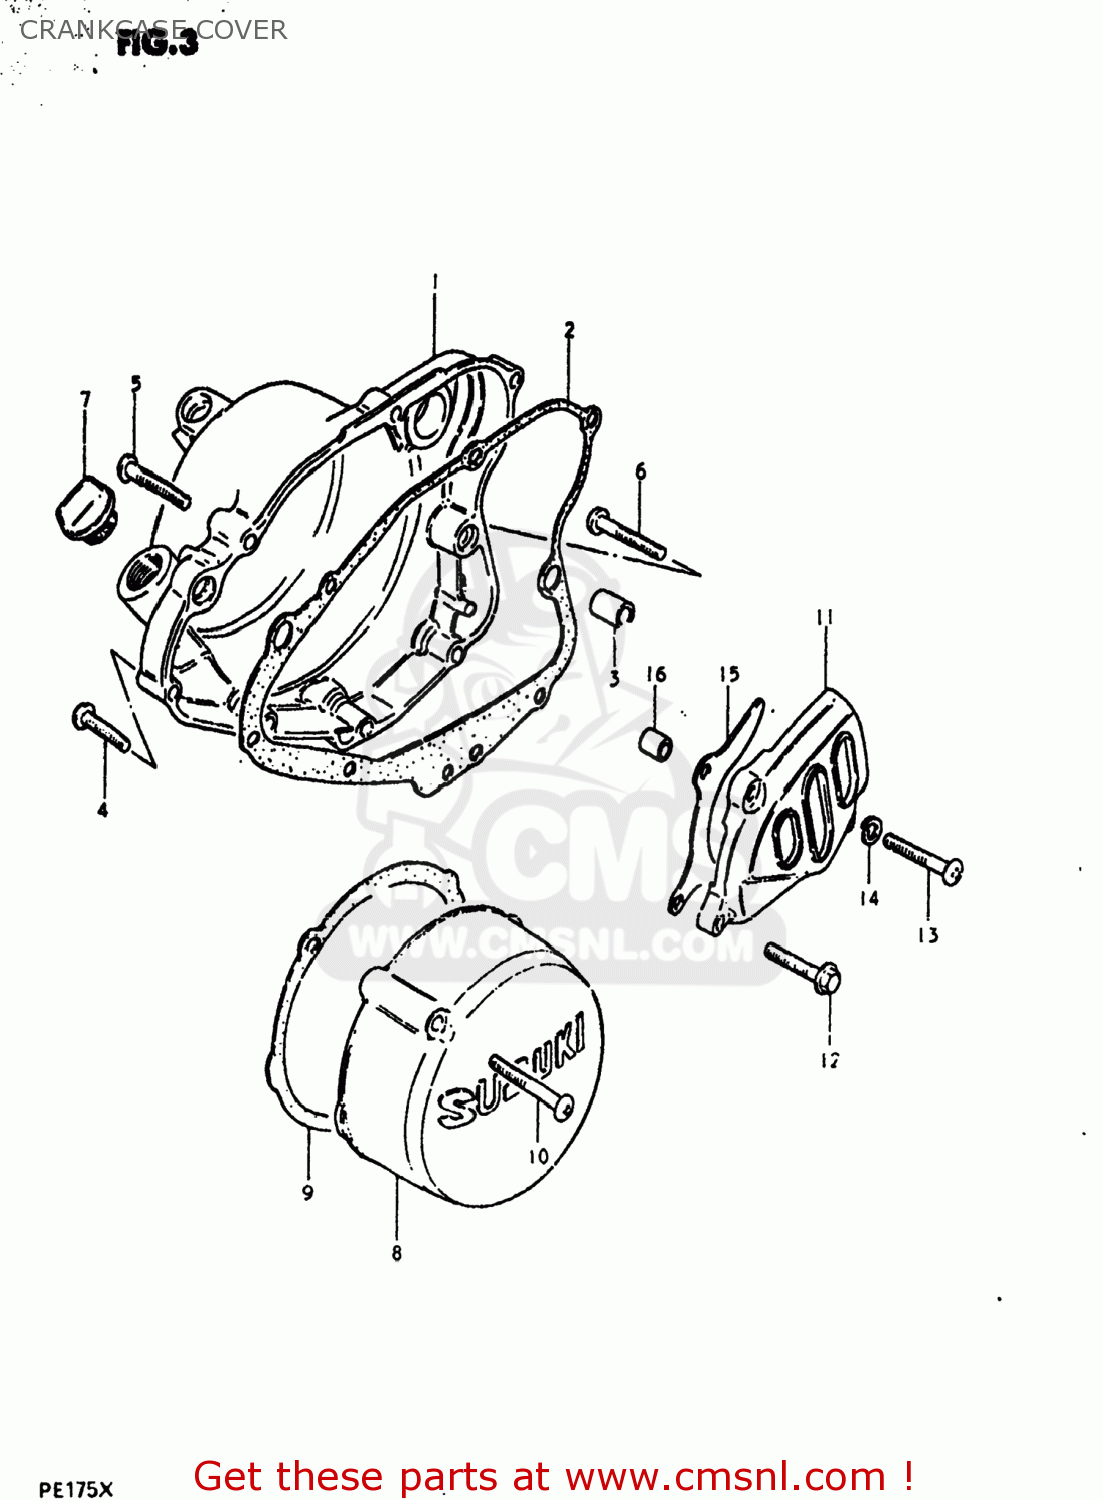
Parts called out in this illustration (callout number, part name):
1	COVER,CLUTCH
2	GASKET,CLUTCH COVER (MCA)
3	PIN
4	SCREW 6X30
5	SCREW
6	SCREW (6X45)
7	PLUG,OIL FILTER
8	COVER,MAGNETO
9	GASKET,MAGNETO COVER (NAS)
10	SCREW
11	COVER,ENGINE SPROCKET
12	BOLT 6X35
13	SCREW (6X45)
14	LOCK WASHER
15	PLATE,CHAIN FRONT GUIDE
16	SPACER(6.5X10.5X12)
